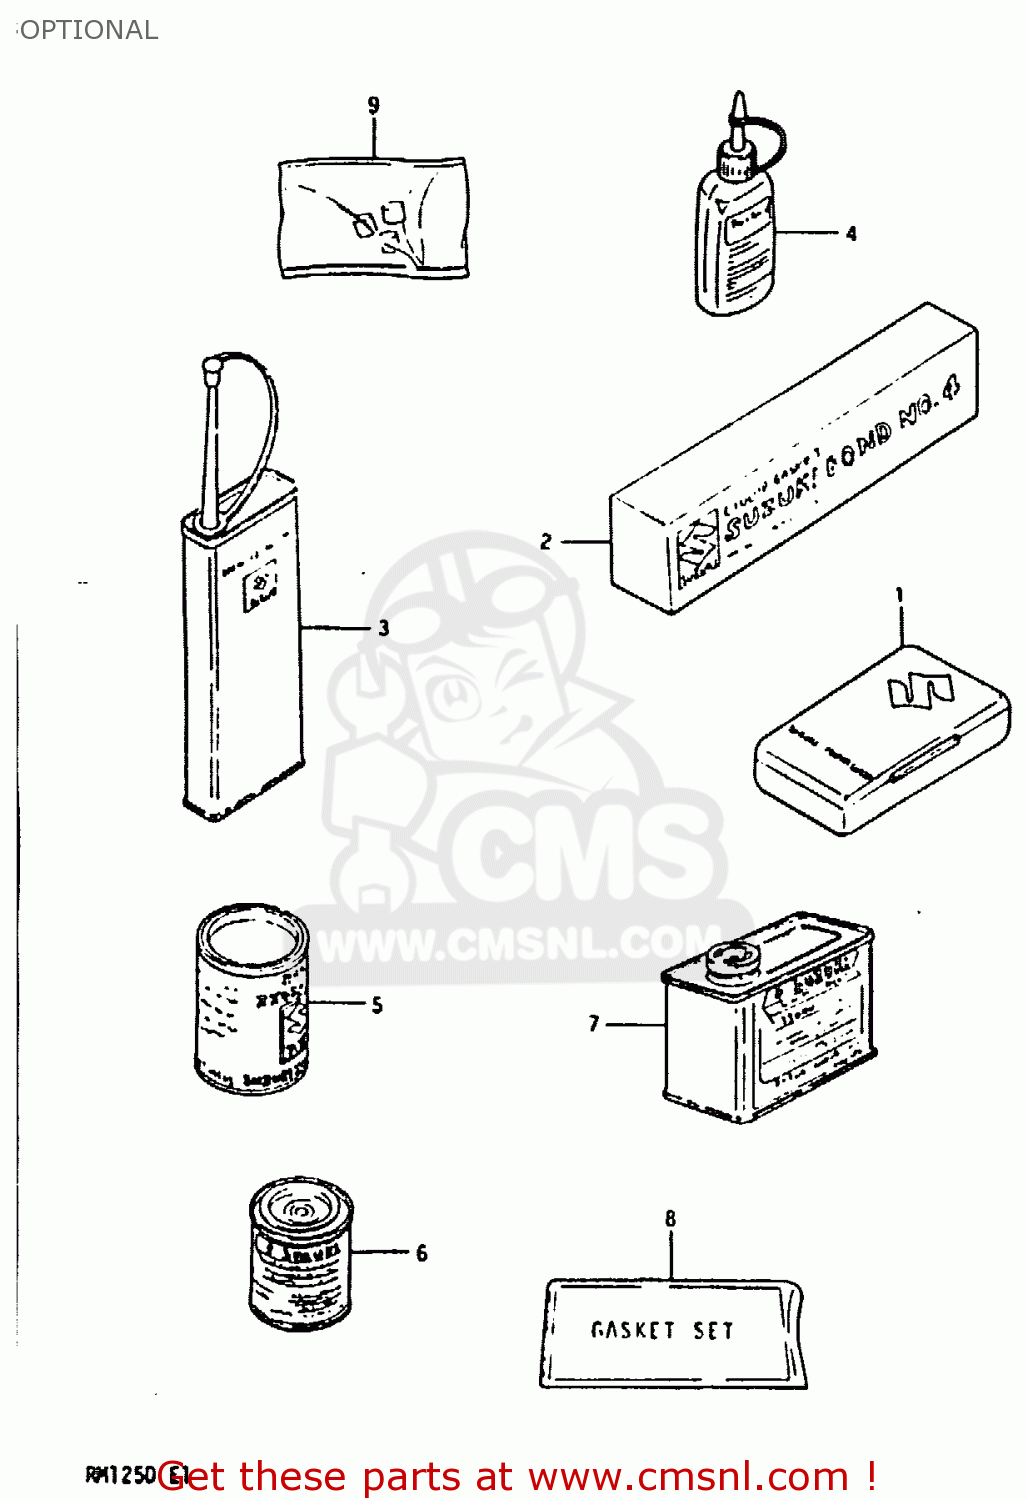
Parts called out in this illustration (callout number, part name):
1	TUBE REPARING TOOL
2	BOND 1104
3	THREAD LOCK NO.1401 CLEAR 200G
4	THREAD LOCK NO
5	GREASE(C)EP2 LITHIUM 150G
6	PAINT,BLACK
7	PAINT (BLACK)
8	GASKET SET
9	ANTI-LEAK ADDITIVE
